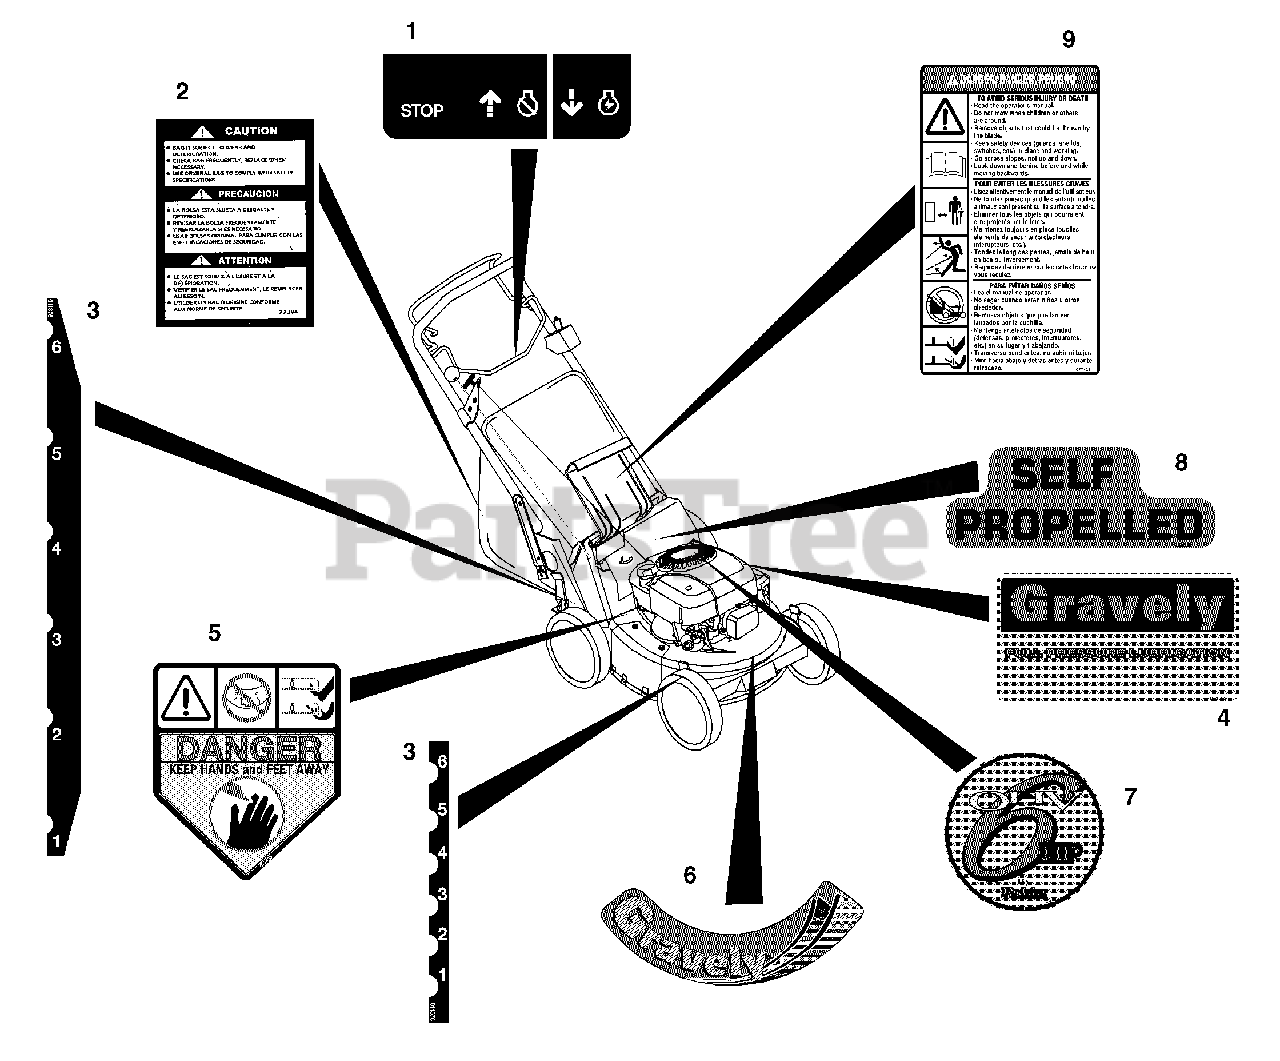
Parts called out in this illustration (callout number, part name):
1	Decal-Engine Control
2	Label-Bagger 21"
3	Decal-Set Height Setting Mower
4	Decal-Gravely Full Press Lube
5	Decal-Danger
6	Decal-Commercial
7	Decal-6.0 H.P. OHV Robin
8	Decal-Self-Propelled
9	Decal-Bilingual Danger
